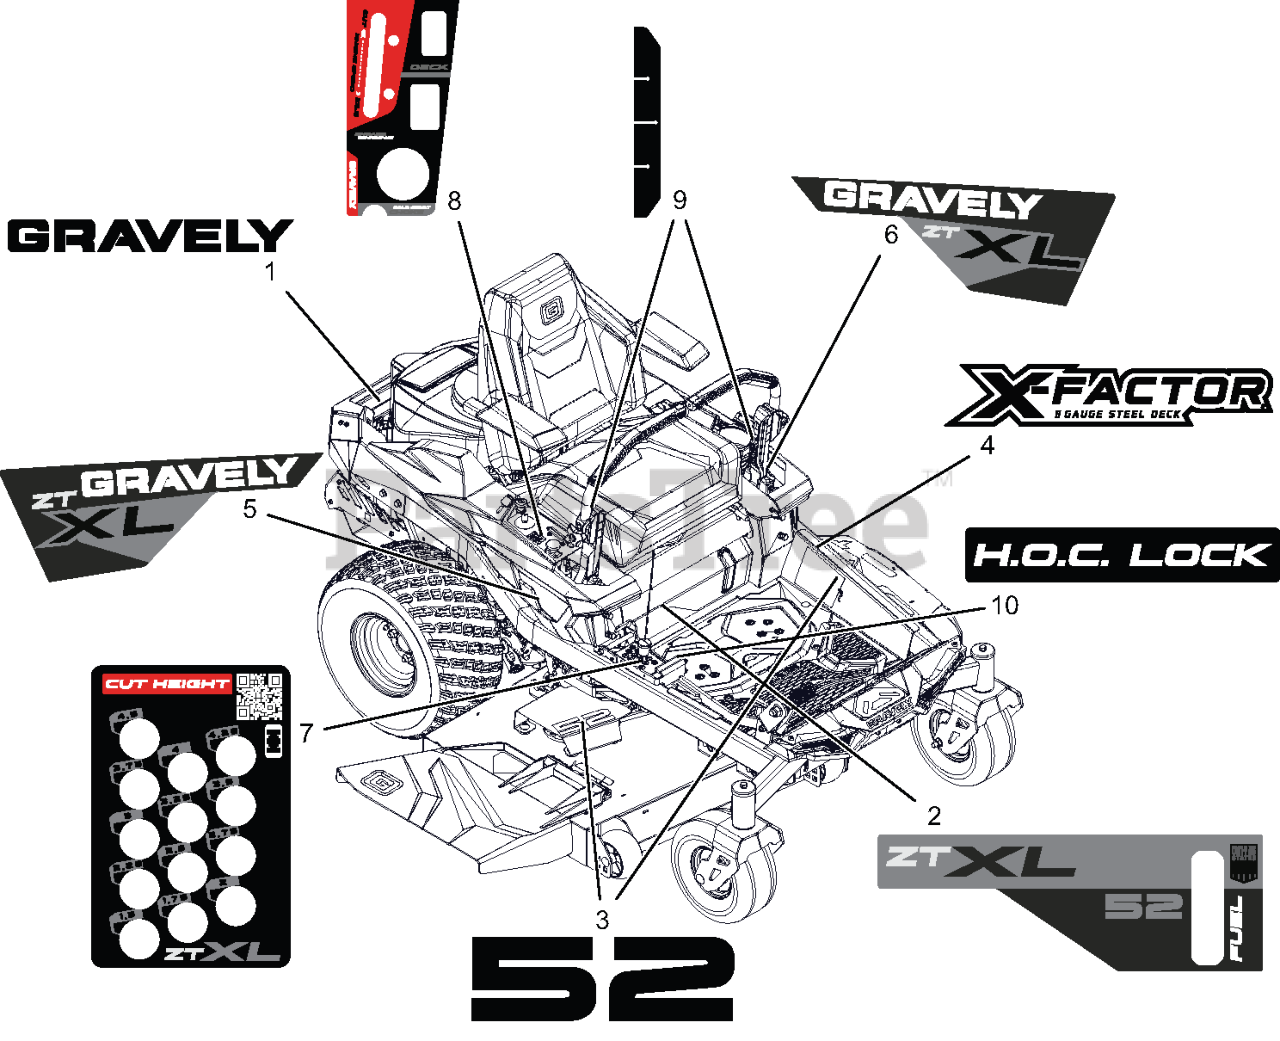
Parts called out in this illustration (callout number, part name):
1	DECAL- GRAVELY
2	DECAL- ZTXL 52-KICK PLATE
3	DECAL- DECK 52"
4	DECAL- DECK X-FACTOR
5	DECAL- ZT XL FENDER RH
6	DECAL- ZT XL FENDER LH
7	DECAL- HEIGHT OF CUT-XL
8	DECAL- CONTROL PANEL-GRAVELY
9	DECAL- HIRTH INDICATOR
10	DECAL- HOC LOCK
